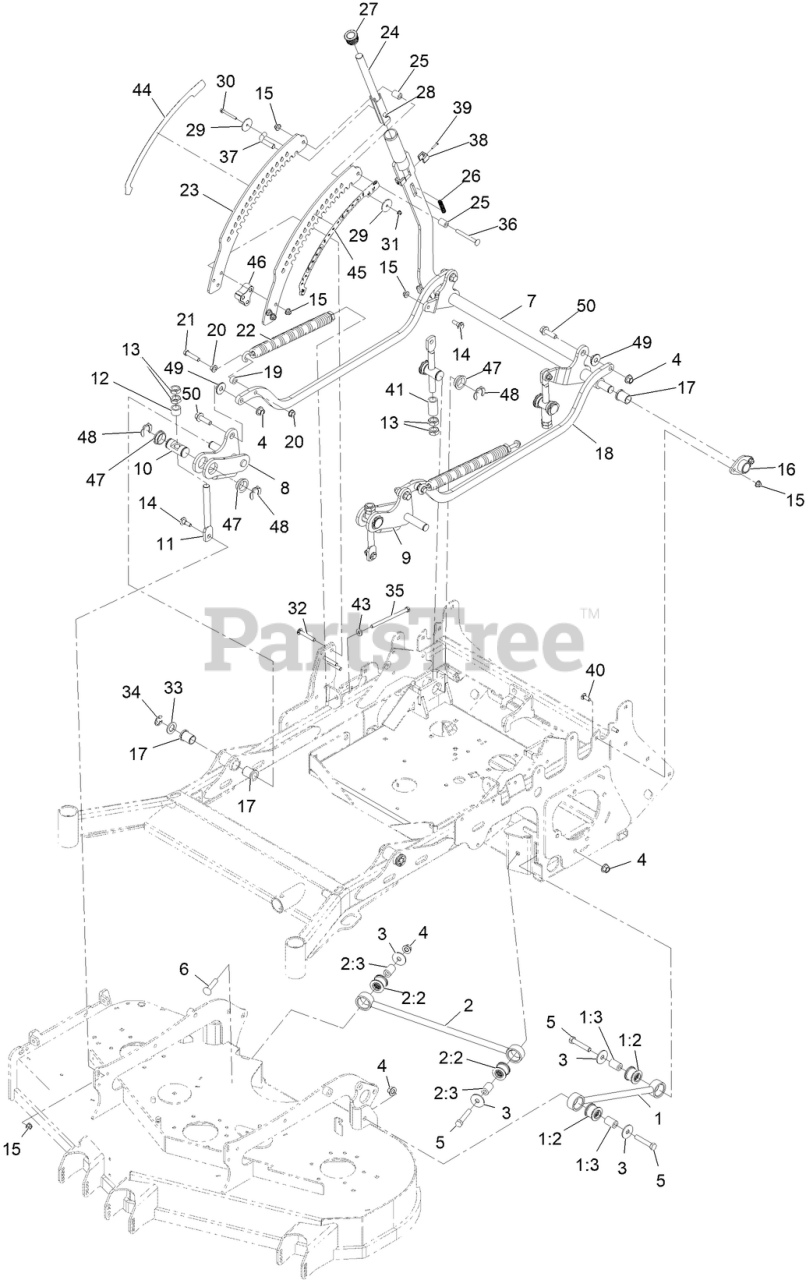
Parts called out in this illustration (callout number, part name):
1	ASM, DECK STRUT
1:2	BUSHING-RUBBER
2	PANHARD ROD ASM
2:2	BUSHING-SUSPENSION, RUBBER
3	WASHER-THRUST
4	Nut-Lock 1/2-13
5	SCREW-HH
6	SCREW-CARR
7	CROSS SHAFT -DECKLIFT-REAR
8	WELD-ARM-DECKLIFT-FRONT-RH
9	WELD-ARM-DECKLIFT-FRONT-LH
10	TRUNION-DECKLIFT GROOVED
11	LINK-DECKLIFT
12	SPACER-DECKLIFT
13	NUT-JAM
14	SCREW-SHOULDER, HHF
15	NUT-HF, NI
16	Support-HOC Shaft
17	BUSHING-FLANGED
18	LINK-HOC 52-60
21	SCREW-HH
22	SPRING-EXTENSION
23	PLATE-HOC
24	ASM-PLUNGER-HOC
25	TUBE-INTERLOCK
27	PLUG-PLASTIC HOC
29	SPACER-HOC
30	SCREW-HHF
32	SCREW-CARR
34	RING-RETAINING, EXT
35	BOLT-TAP, HH
36	SCREW-CARR
37	PIN-HOC
38	CHANNEL-HOC GUIDE
39	SCREW-SHWH
40	SCREW-CARR
41	SPACER 1.13 O.D. X .81 I.D. X 2.05L
44	DECAL-HEIGHT OF CUT,OUTER
45	DECAL-HEIGHT OF CUT-INNER
46	SPACER-HOC VERTEX
47	BUSHING-FLANGED HOC
48	E-RING WIDE GRIP
50	SCREW-HHF
